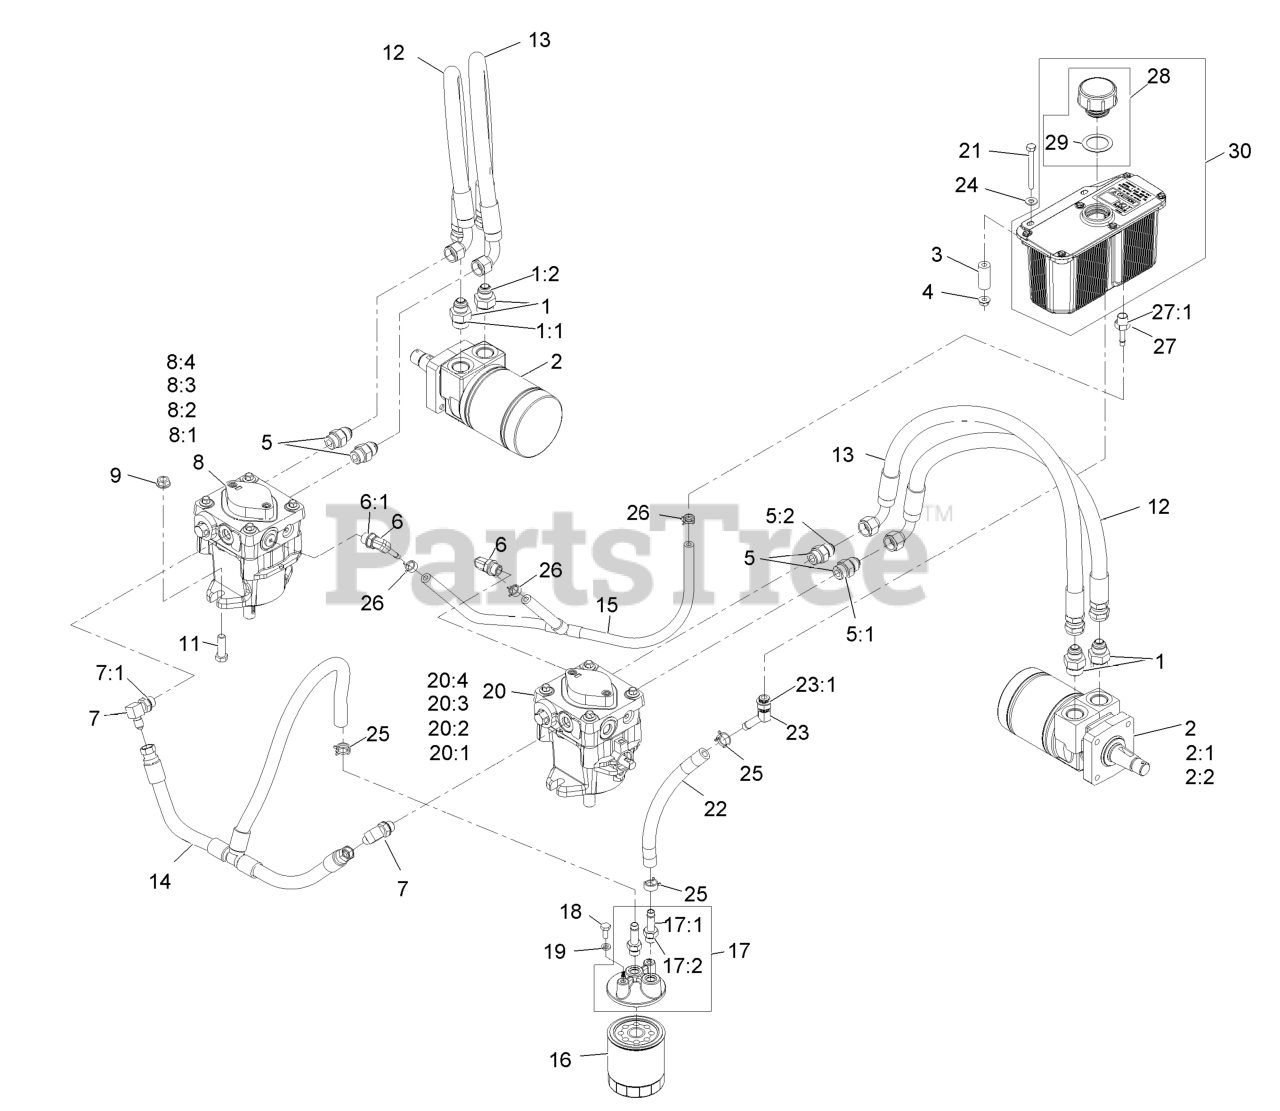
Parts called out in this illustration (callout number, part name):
1	FITTING-STRAIGHT
2	HYD MOTOR ASM
2:1	BEARING AND SEAL KIT
2:2	SEAL KIT
5	FITTING-STRAIGHT
6	ELBOW-90 DEG
7	FITTING-ELBOW, 90 DEG
8	LH HYD PUMP ASM
8:1	INPUT SHAFT KIT
8:2	BEARING-THRUST
8:3	CYLINDER BLOCK KIT
8:4	SEAL OVERHAUL KIT
9	NUT-FLANGE
11	SCREW-HH
12	HYD HOSE ASM
13	HYD HOSE ASM
14	CHARGE HOSE ASM
15	CASE DRAIN HOSE ASM
16	FILTER-25 MICRON, BI-DIRE
16	ELEMENT-FILTER, WINTER
17	FILTER HEAD ASM
17:1	ADAPTER-STRAIGHT
18	SCREW-HH
19	WASHER-LOCK
20	RH HYD PUMP ASM
20:1	INPUT SHAFT KIT
20:2	BEARING-THRUST
20:3	CYLINDER BLOCK KIT
20:4	SEAL OVERHAUL KIT
21	SCREW-HH
22	HOSE-CHARGE
23	FITTING-BARBED, 45 DEG
24	WASHER-FLAT
25	CLAMP-HOSE
26	CLAMP-HOSE
27	ADAPTER-STRAIGHT
28	KIT,HYD RES CAP W/GASKET
29	GASKET-CAP
30	HYD RESERVOIR ASM
